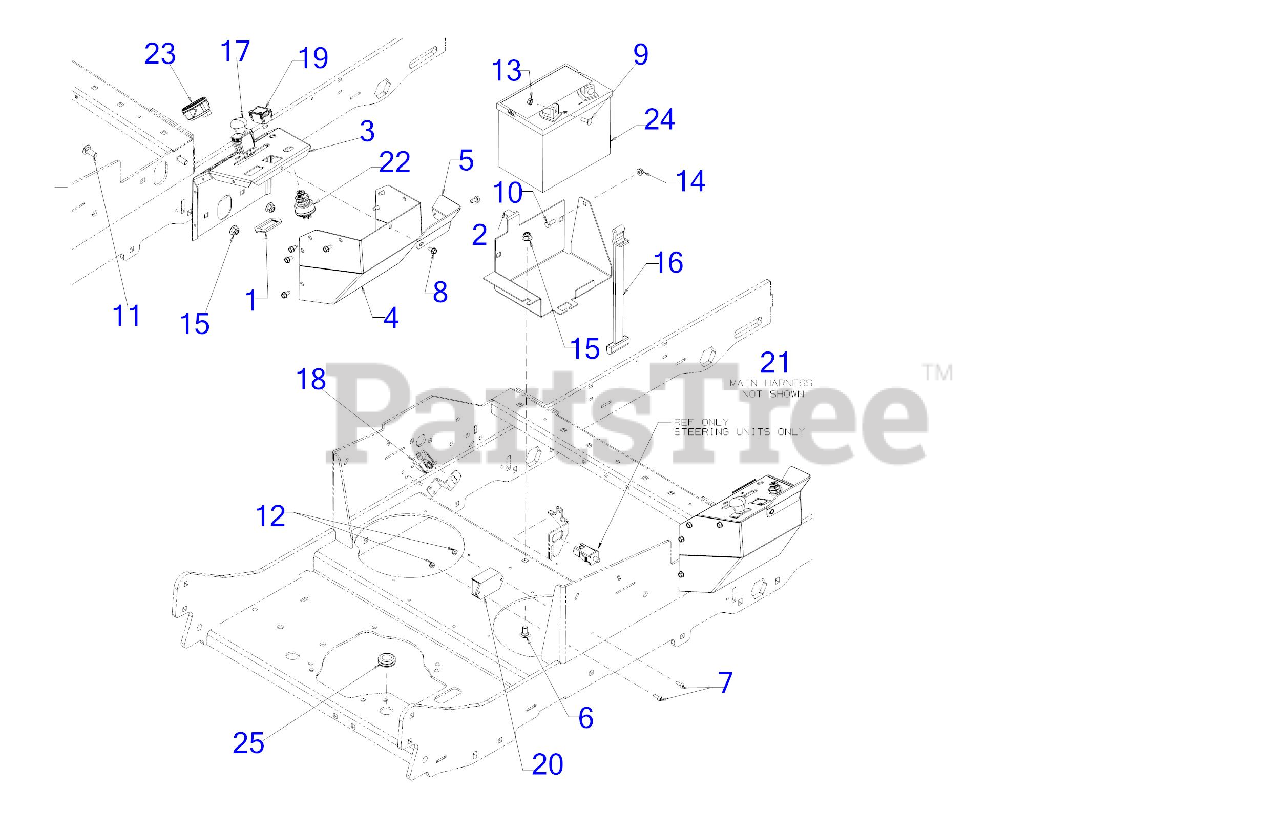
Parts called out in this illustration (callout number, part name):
1	BRACKET-PTO SWITCH
6	CARRIAGE BOLT 3/8-16 x .750 GR5
7	SCREW #10-24 x .62
8	SCREW 1/4-20 X.500
9	SCREW 1/4-20 x .75 GR5
10	SCREW 1/4-20X.75 GR5
11	CARRIAGE BOLT 3/8-16 x 1.00 GR5
13	SEMS NUT 1/4-20
14	FLANGE LOCK NUT
16	BATTERY RETAINER STRAP
17	PTO SWITCH (BLACK KNOB) TEXT SYM
18	3 POLE SWITCH ( NC-NO-NO)
20	CONTROL PANEL (SOFT CLUTCH)
21	WIRE HARNESS ASSEMBLY KOH/KAW EFI
22	KEY SWITCH (3 POSITION)
23	DUAL FUEL GAUGE
24	Purchase Battery Locally
25	RUBBER GROMMET
